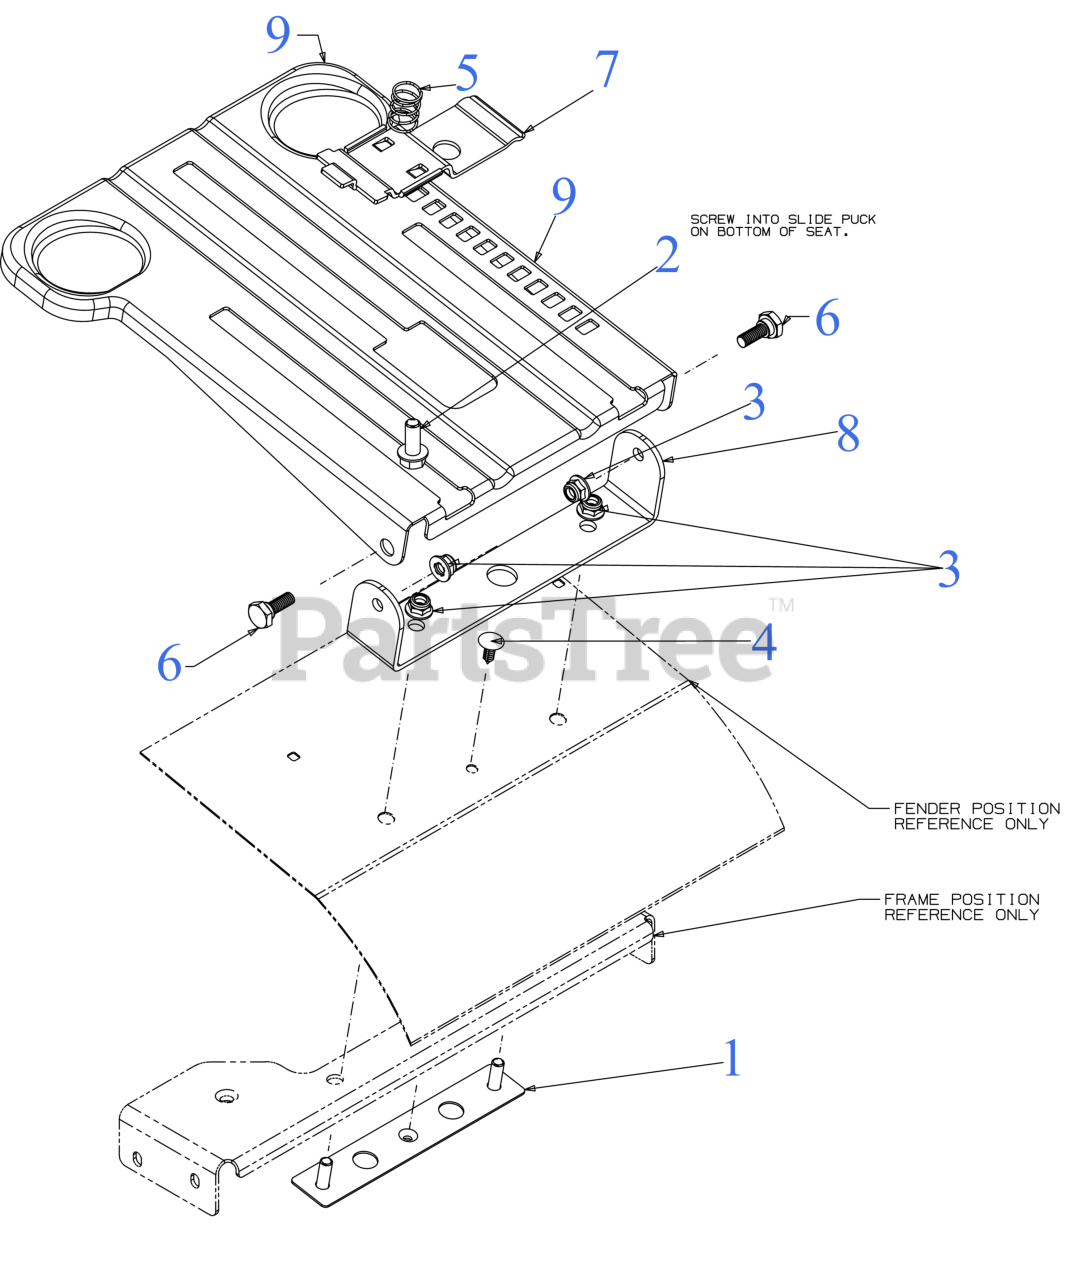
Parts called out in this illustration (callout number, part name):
1	PIVOT BRACKET PLATE
2	SCREW 3/8-16 X .875 GR5
3	FLANGE LOCK NUT 5/16-18
4	RATCHET CLIP .250
5	COMPRESSION SPRING
6	SHOULDER SCREW .44DIAx.18 5/16-18
7	SEAT ADJUST LEVER
